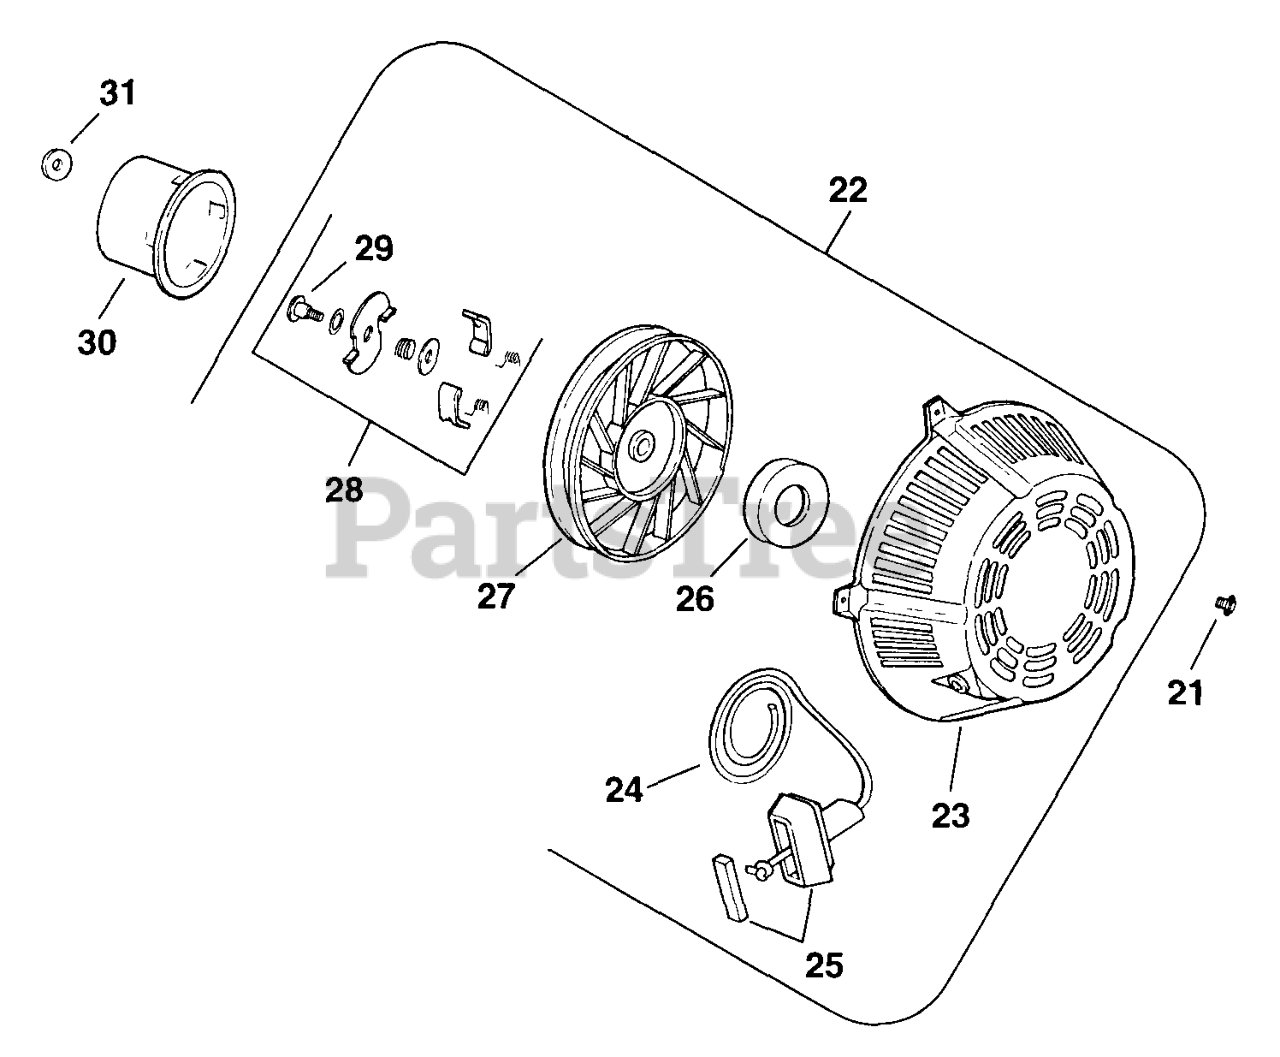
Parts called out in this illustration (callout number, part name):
21	SCREW, FLG HD 10-24X1/4"
22	STARTER ASSY,RETRACTABLE-USE 12 165 03-S
23	HOUSING - DISCONTINUED
24	ROPE - DISCONTINUED
25	HANDLE - USE 25 166 01
26	SPRING & KEEPER - (#DSC)
27	PULLEY - (#DSC)
28	KIT, DOG REPAIR - (#DSC)
29	SCREW - DISCONTINUED
30	CUP
31	WASHER, FLAT 13/32" - DISCONTINUED
